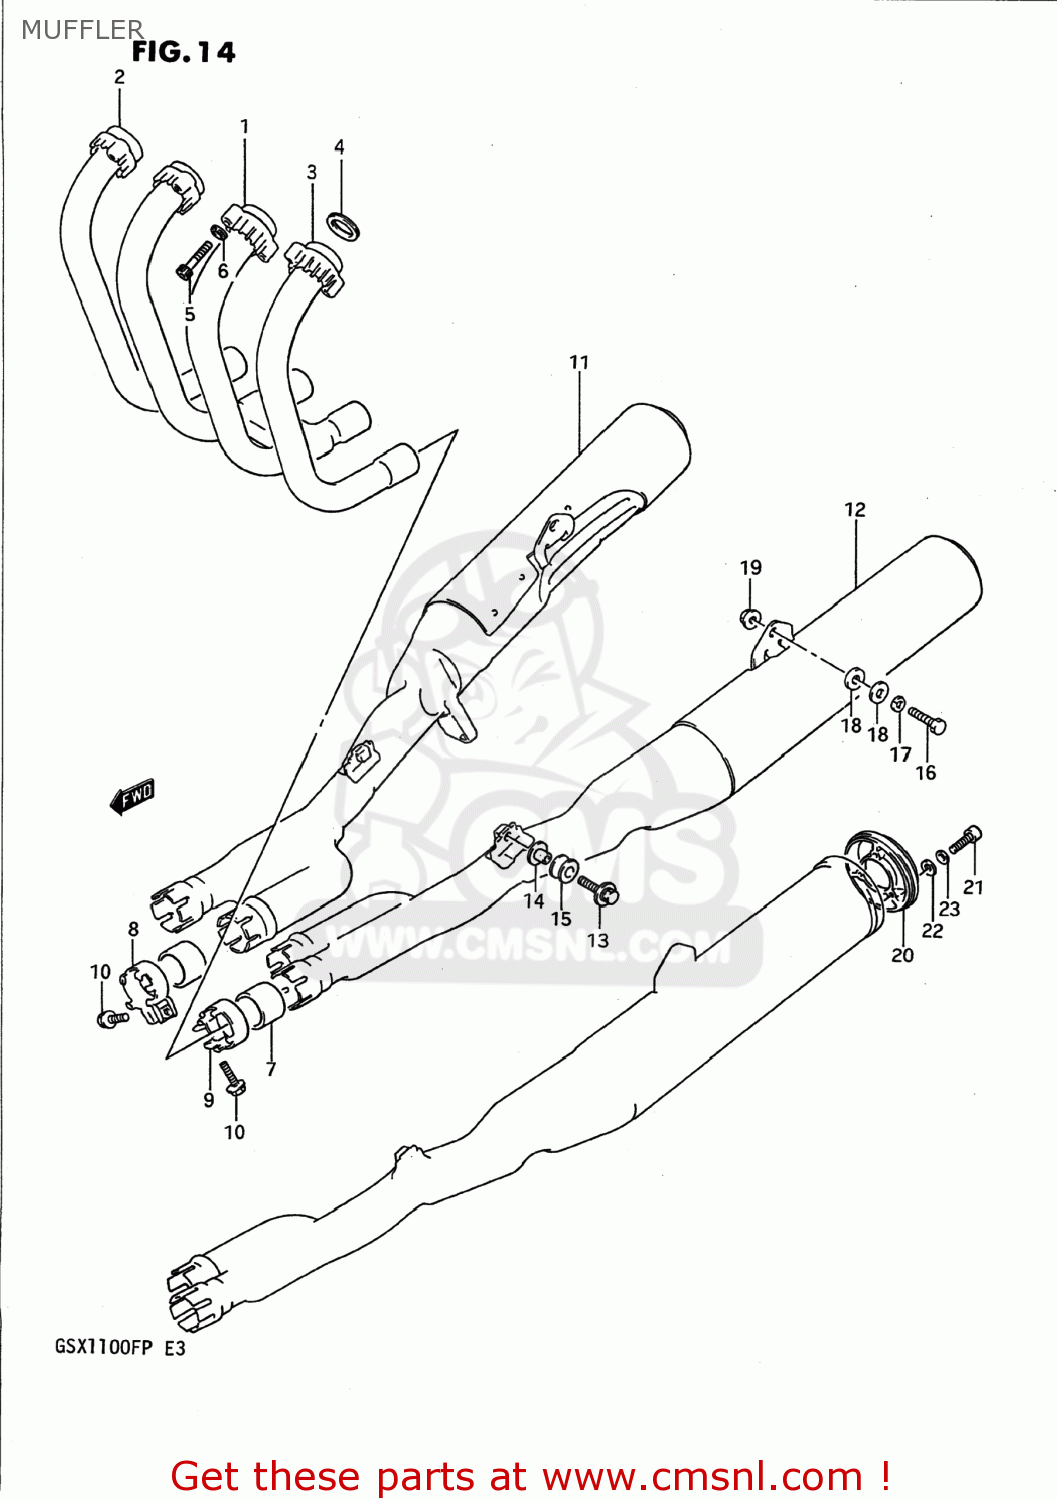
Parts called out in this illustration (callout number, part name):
1	EXHAUST ASSY,CTR
2	PIPE,EXHAUST,R
3	PIPE COMP,EXHAUST,LEFT
4	GASKET,EXHAUST (NAS)
5	BOLT 8X35
6	WASHER
7	CONNECTOR,MUFFLER
8	CLAMP,MUFFLER CONNECTOR
9	CLAMP,MUFFLER CONNECTOR
10	BOLT
11	MUFFLER ASSEMBLY
12	MUFFLER ASSEMBLY
13	BOLT 8X35
14	SPACER(8.6X12X17.5)
15	CUSHION
16	BOLT
17	WASHER,LOCK,10
18	WASHER
19	NUT
20	COVER,MUFFLER TAIL
21	BOLT(6X15)
22	WASHER(7X12X1)
23	WASHER
